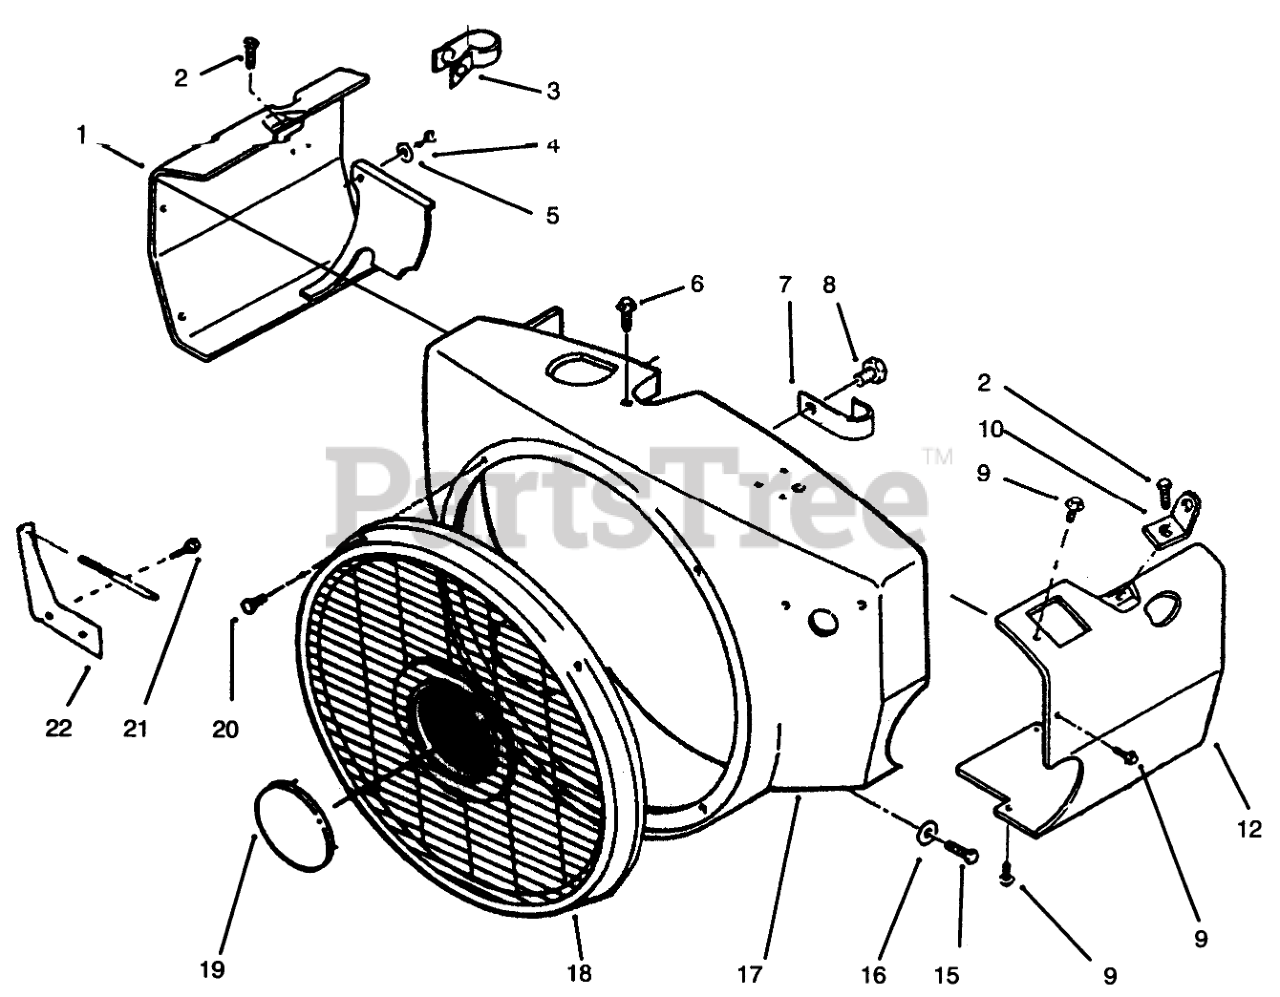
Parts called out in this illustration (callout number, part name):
1	LH AIR CYLINDER HSG
2	SCREW-HWH
3	WIRE CLAMP
4	SCREW-HH
5	WASHER-FLAT
6	HEX HD CAPSCREW
7	CLIP-WIRE
8	SCREW-HWH
9	SCREW-HWH
10	BRACKET-LIFTING
12	RH AIR CYLINDER HSG
15	SCREW-HH
16	WASHER-FLAT
17	BLOWER-HOUSING
18	GUARD-STATIONARY
19	NAME-PLATE TORO LOGO
20	SCREW-PAN HEAD
21	SCREW-HWH
22	BRACKET
